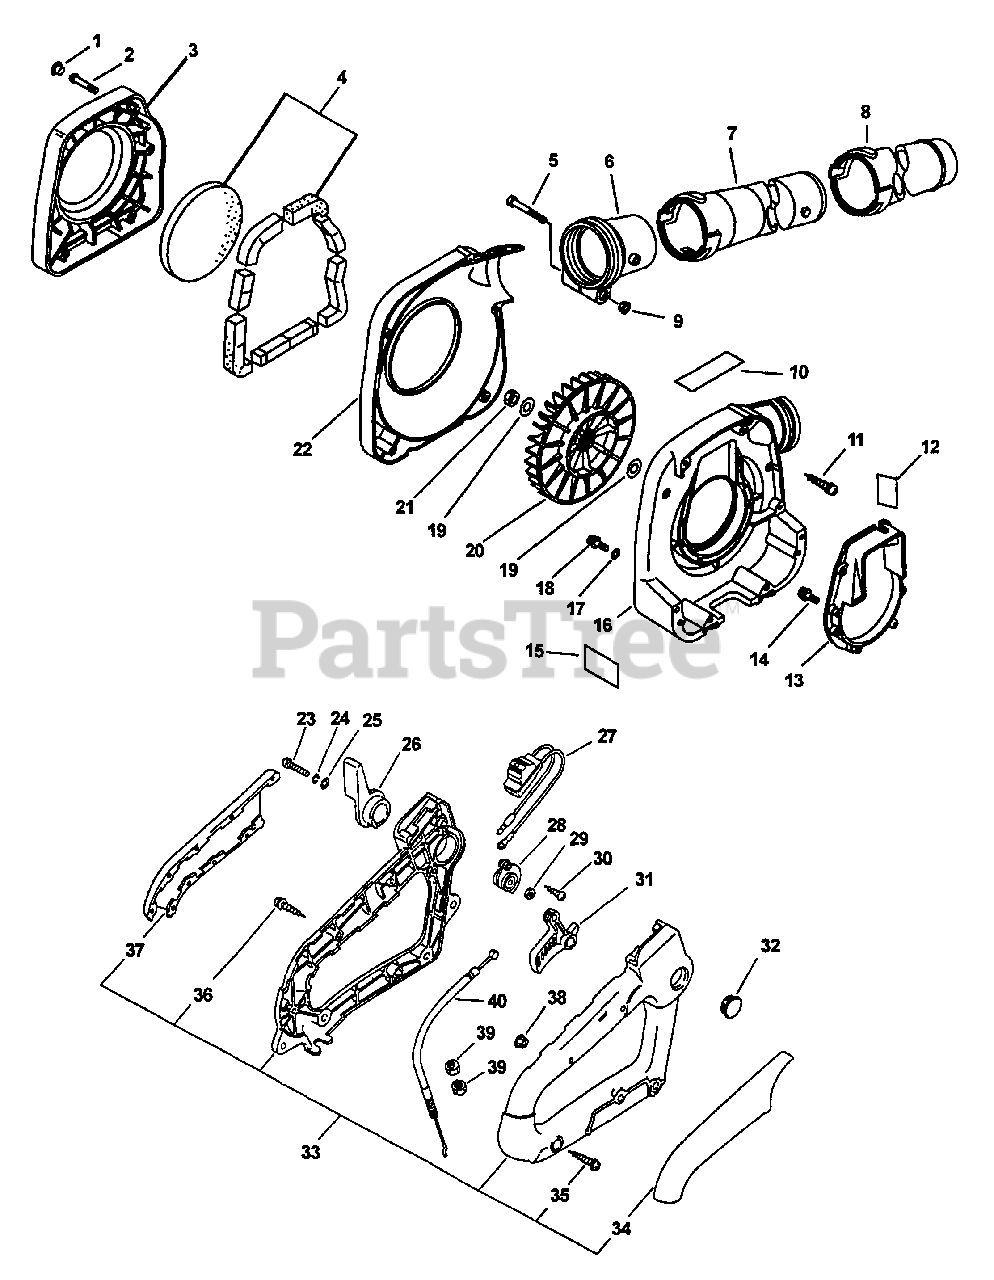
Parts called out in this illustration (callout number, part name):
1	PLUG
3	GRID, FAN CASE
4	PAD, FOAM ASSY (8 PCS)
5	BOLT 5×60
6	ADAPTER, TUBE
7	TUBE, BLOWER - STRAIGHT
8	TUBE, BLOWER - NOZZLE
9	NUT, FLANGE M5
10	LABEL - NOISE
11	SCREW 5×30
12	LABEL - CAUTION -- SPANISH
13	BRACKET, ENGINE
14	SCREW - 4×18
15	LABEL, CAUTION - HOT
16	CASE, FAN
18	SCREW 4×22
20	FAN
22	COVER, FAN - LEFT
23	SCREW 6×20
24	WASHER, SPRING 6
25	WASHER 6.5×13×1
26	CONTROL, THROTTLE
27	IGNITION SWITCH ASSY
28	BRACKET, THROTTLE
29	NUT, HEX M6
30	SCREW 4×10
31	TRIGGER, THROTTLE
33	HANDLE KIT
34	GRIP, RIGHT
35	SCREW 5×35
36	SCREW 4×22
37	GRIP, LEFT
38	NUT, FLANGE M5
40	CABLE, THROTTLE
